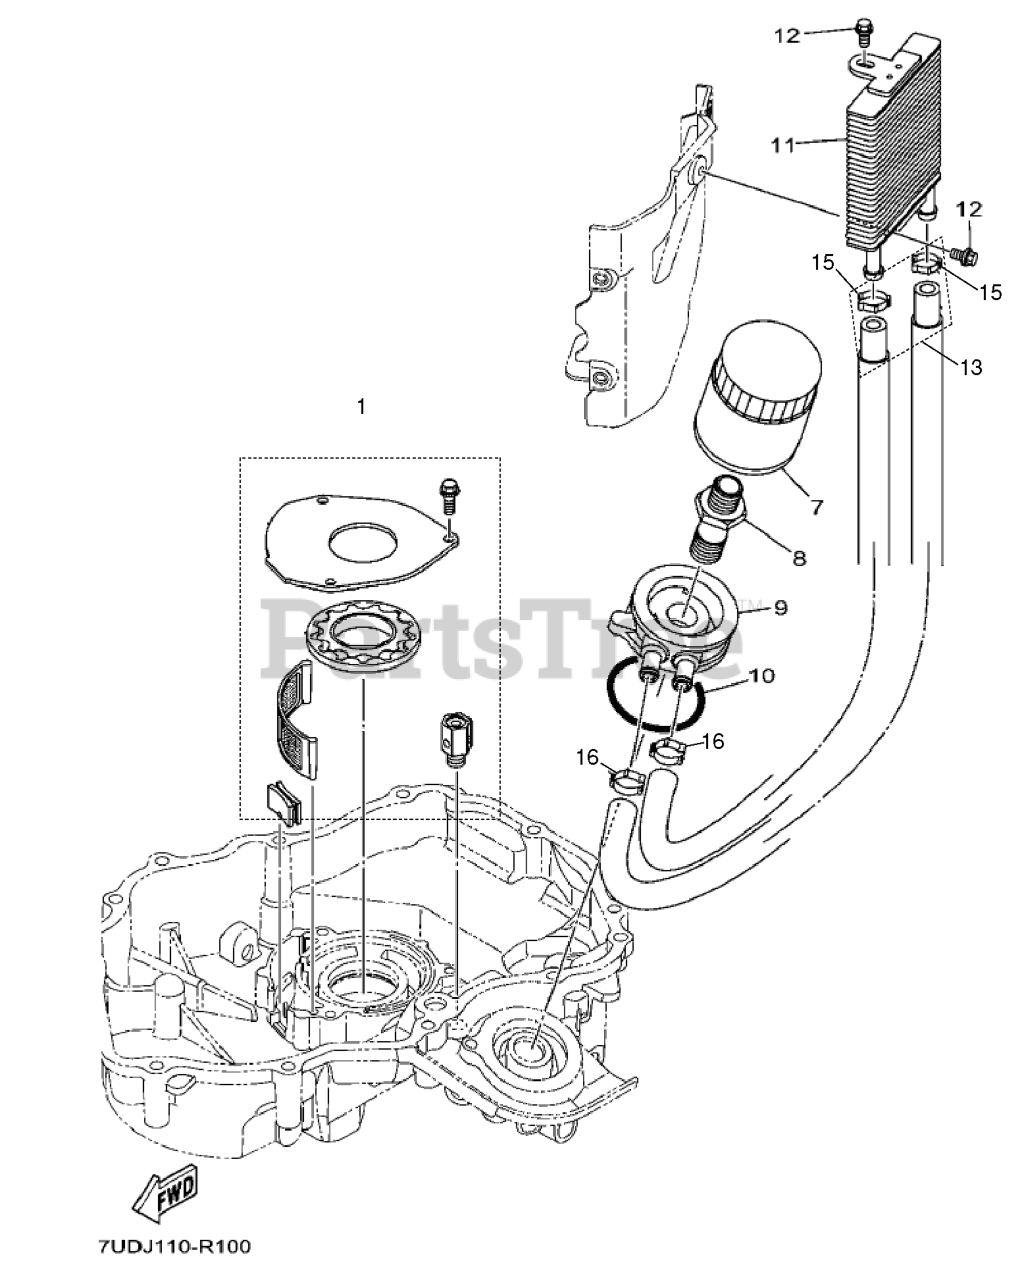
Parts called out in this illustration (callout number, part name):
7	OIL FILTER ELEMENT ASSY YAMAHA
8	BOLT YAMAHA PN: 7UD-E7056-00
10	SEAL 1 YAMAHA PN: 7UD-E358B-00
11	OIL COOLER ASSY YAMAHA PN: 7UD
12	BOLT YAMAHA PN: 95822-06010
13	OIL COOLER HOSE KIT
